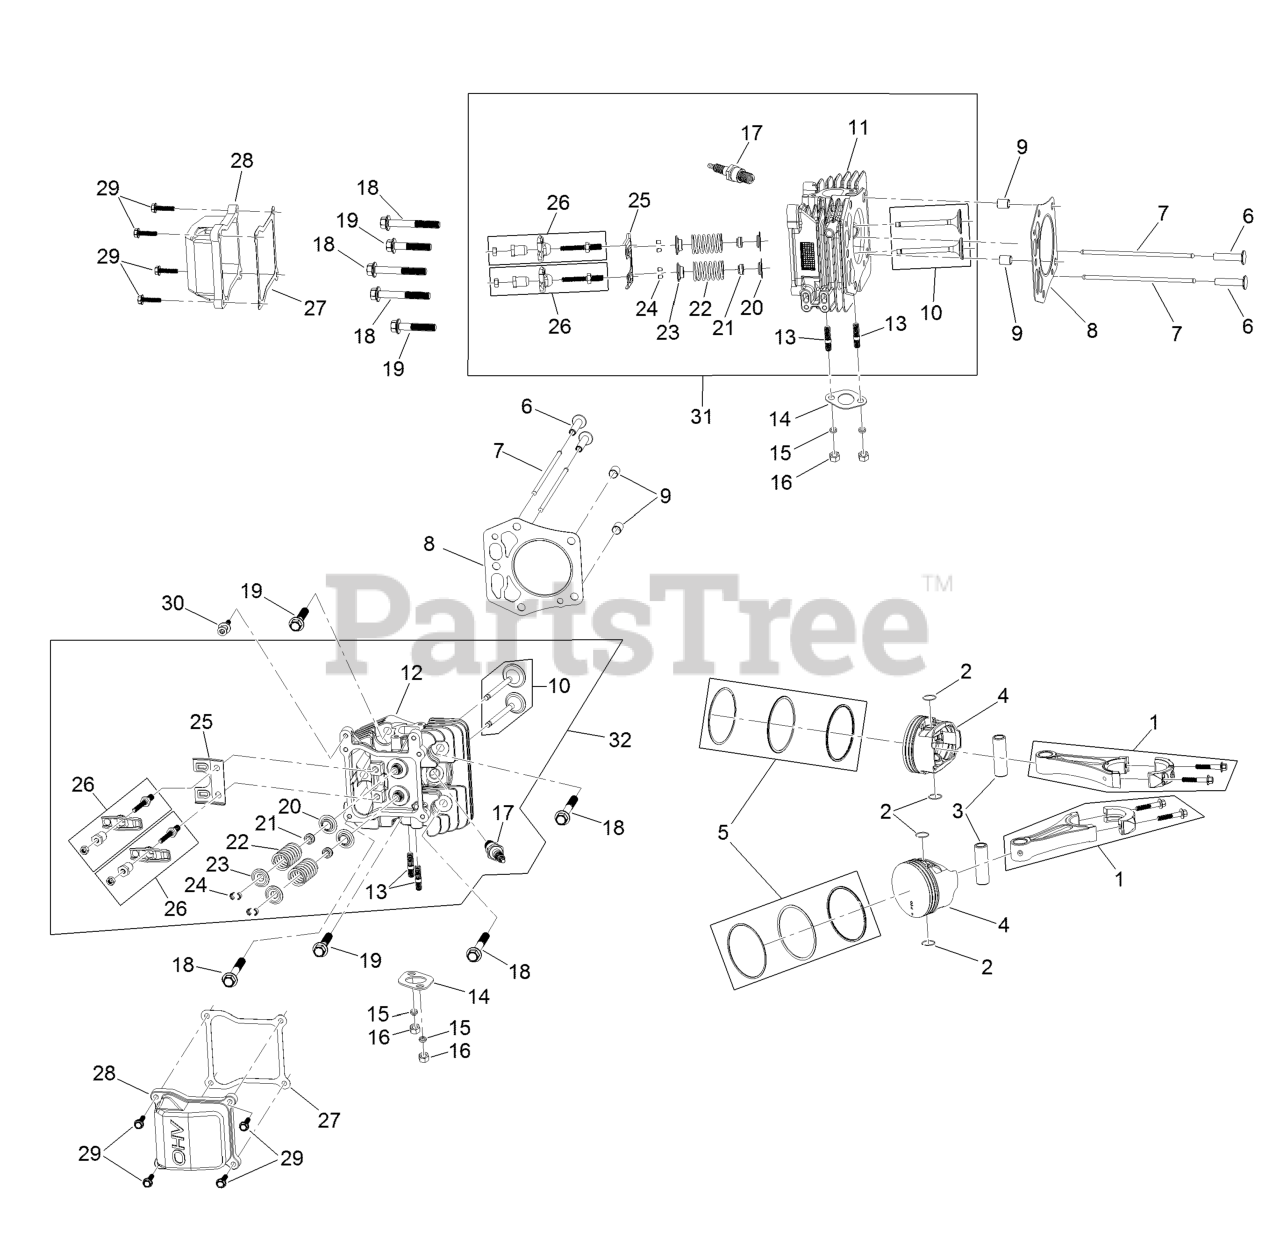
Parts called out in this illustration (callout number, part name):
1	Connecting Rod ASM
2	Clip-Pin, Piston
3	Pin-Piston
5	Piston Ring Set
6	Lifter-Valve
7	Rod-Push
8	Gasket-Head, Cylinder
9	Pin-Dowel
10	Valve Set
11	Head-Cylinder, Right
12	Head-Cylinder, Left
13	Stud-Exhaust
14	Gasket-Exhaust
15	Washer-Lock, Split
17	Spark Plug
18	Screw-HWH
19	Screw-HWH
20	Seat-Spring, Valve
21	Seal-Stem, Valve
22	Spring-Valve
23	Retainer-Spring, Valve
24	Keeper-Valve
25	Plate-Guide, Push Rod
26	Rocker Arm ASM
27	Gasket-Valve Cover
28	Cover-Valve
29	Screw-HHF
30	Screw-Shoulder, HH
31	Right Head ASM
32	Left Head ASM
